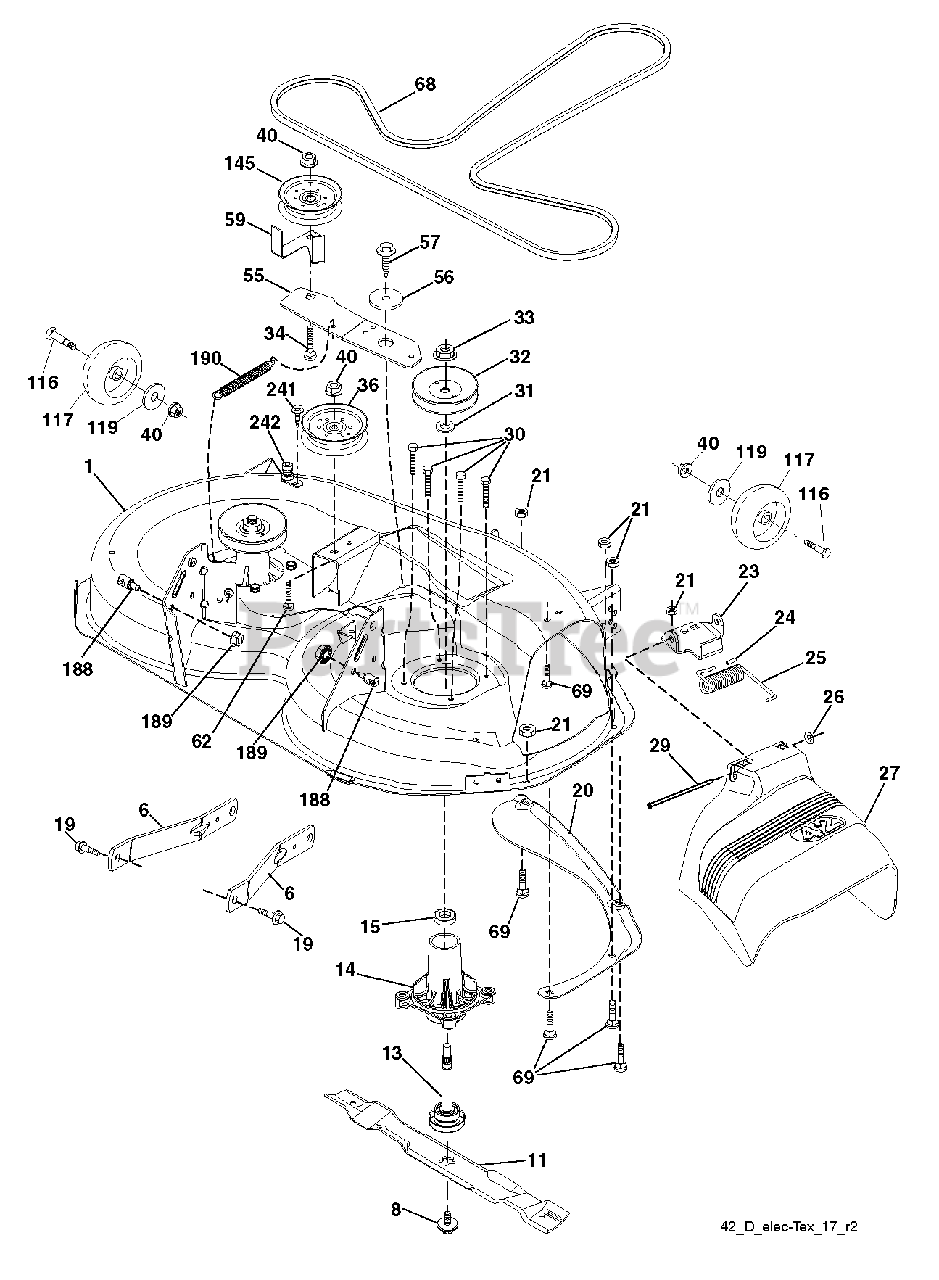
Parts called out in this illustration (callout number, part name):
1	DECK.WELDMENT.42"
6	ARM.SUSPENSION.MOWER.R
8	BOLT.WASHER.ASM.7/16-2
11	42" HI-LIFT BLADE
13	SHAFT.ASM.MDRL.N/GREASE.38
14	HOUSING MANDREL
19	BOLT.SHOULDER
20	BAFFLE.VORTEX
21	LOCKNUT
23	BRKT.DEFLECTOR.38"2005+
24	CAP-SLEEVE LT
25	SPRING.TORSION.DEFLECT
26	NUT PUSH M
27	SHIELD.DEFLECTOR.MOWER.42"BLAC
29	ROD.HINGE
30	SCREW, WASHER HEAD
31	WASHER.SPACER.MANDREL
32	PULLEY/MANDREL
33	NUT.FLANGE.LOCK.TOP
34	BOLT.3/8-16X1.50
36	PULLEY.IDLER.2006
40	NUT LOCK FLG 3/8-16 UNC
55	IDLER.ARM
56	SPACER.RETAINER
57	SCREW 3/8-16X1
59	GUARD, BELT
62	BOLT
68	BELT V SECONDARY
69	BOLT
117	WHEEL.GAGE.HALF.SPOKED
119	WASHER
145	PULLEY.IDLER.48"PRIMARY
188	STUD.FASTNER.W/ANTI-ROTATE
189	NUT LOCK HEX FLANGE 5/16-18
190	SPRING.MOWER.DRIVE.ELECTRIC
242	PORT.WASHOUT
